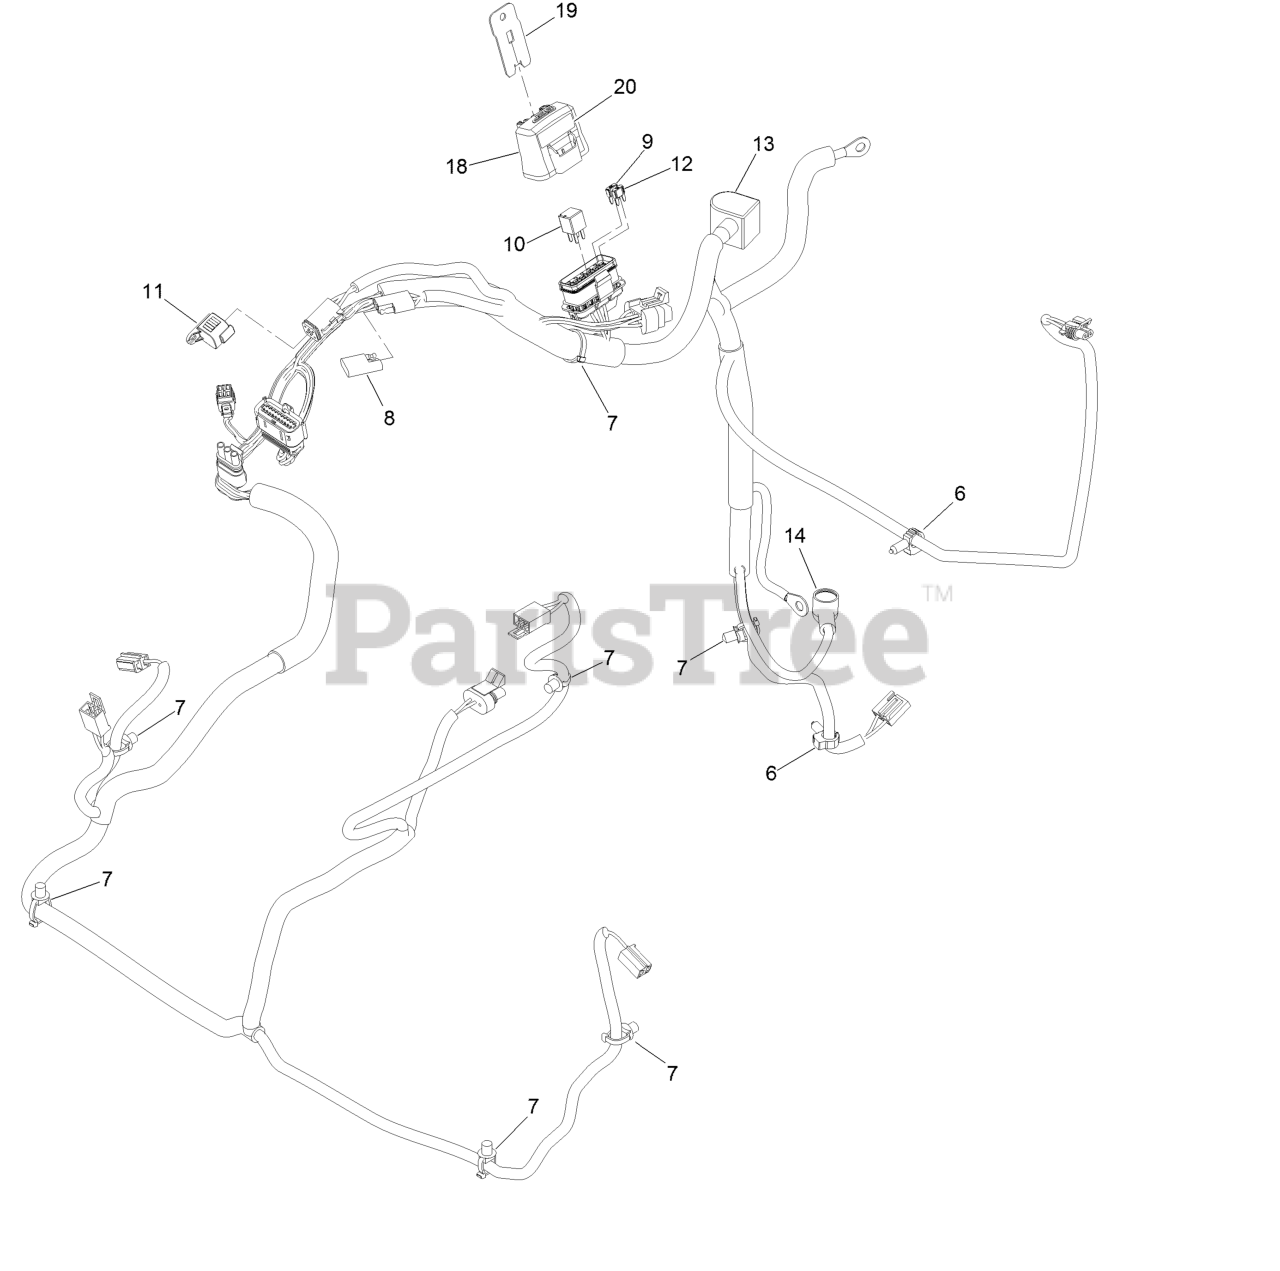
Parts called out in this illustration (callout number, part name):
6	Clip-Harness
7	Clip-Tie
8	Cap-Plug
9	Fuse-Mini Blade, 20 Amp
10	Relay-Micro
11	Cap-Plug, 6 Way
12	Fuse-Mini Blade, 15 Amp
13	Insulator-Battery
14	Insulator-Solenoid
18	Cover-Block, Fuse
19	Clip-Mounting
20	Decal-Fuse
